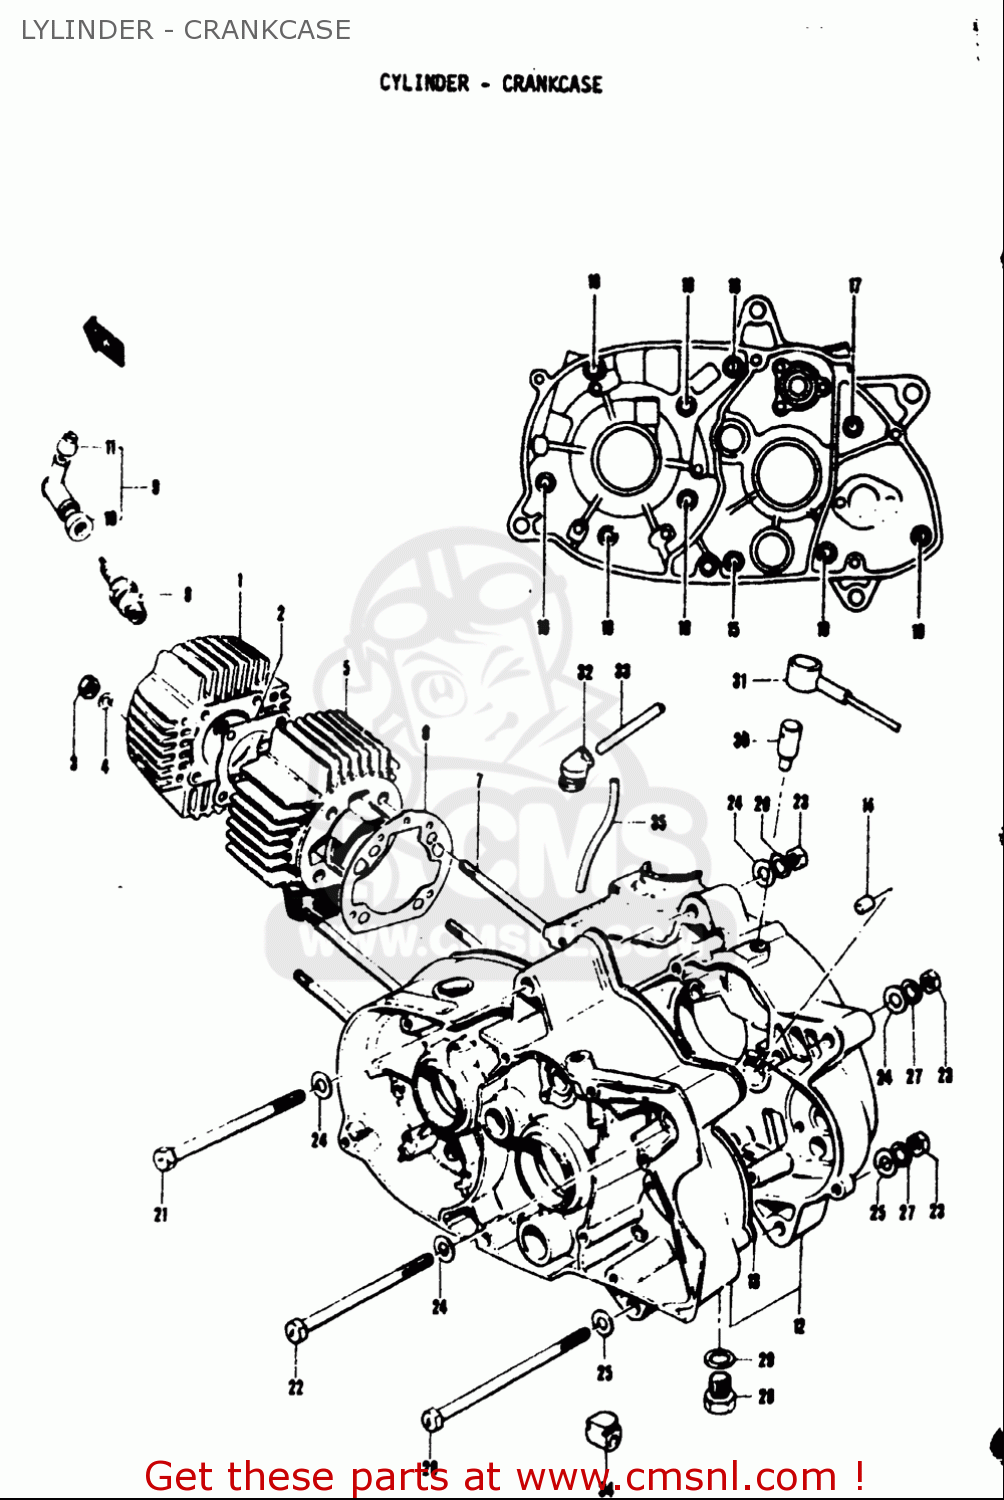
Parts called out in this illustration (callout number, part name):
2	GASKET,CYLINDER HEAD (NAS)
3	NUT
4	WASHER
5	CYLINDER
6	GASKET,CYLINDER (NAS)
7	BOLT,STUD
8	PLUG,SPARK(B7HS)
11	SEAL,HIGH TENSION CORD
13	GASKET,CRANKCASE (NAS)
14	PIN
15	SCREW
16	SCREW
17	SCREW
18	SCREW
19	SCREW
21	BOLT(8X105)
22	BOLT 8X100
23	NUT
24	WASHER
25	WASHER
26	WASHER,LOCK
27	WASHER,LOCK
28	PLUG(MAGNETO)
29	GASKET(14X19.2X2) (NAS)
30	PLUG,T/M BREATHER
31	GASKET (NAS)
33	HOSE(5X9X600)
34	GROMMET
